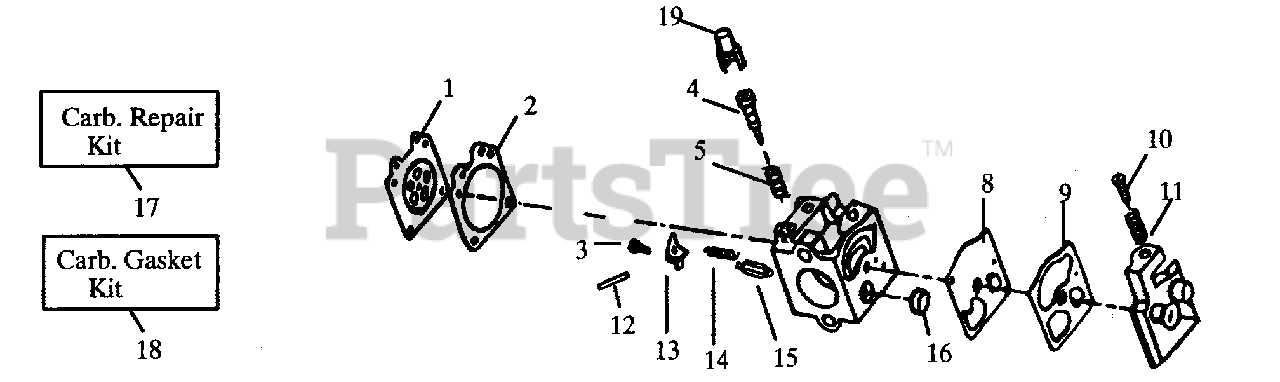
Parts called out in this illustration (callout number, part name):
1	Metering Diaphragm
2	WT-141 - T 1
2	WT-141A - T 2
3	Metering Lever Pin Screw
4	WT-141 - T 1
5	WT-141 - T 1
5	WT-141A - T 2
8	Fuel Pump Diaphragm
9	Fuel Pump Gasket
10	Idle Speed Screw
11	Idle Speed Spring
12	Metering Lever Pin
13	Metering Lever
14	WT-141 - T 1
14	WT-141A - T 2
15	Inlet Needle Valve
16	Fuel Inlet Screen
17	Carb. Kwik Repair Kit
18	Carb. Gasket/Diaphragm Kit
19	Limiter Cap (Gold)
